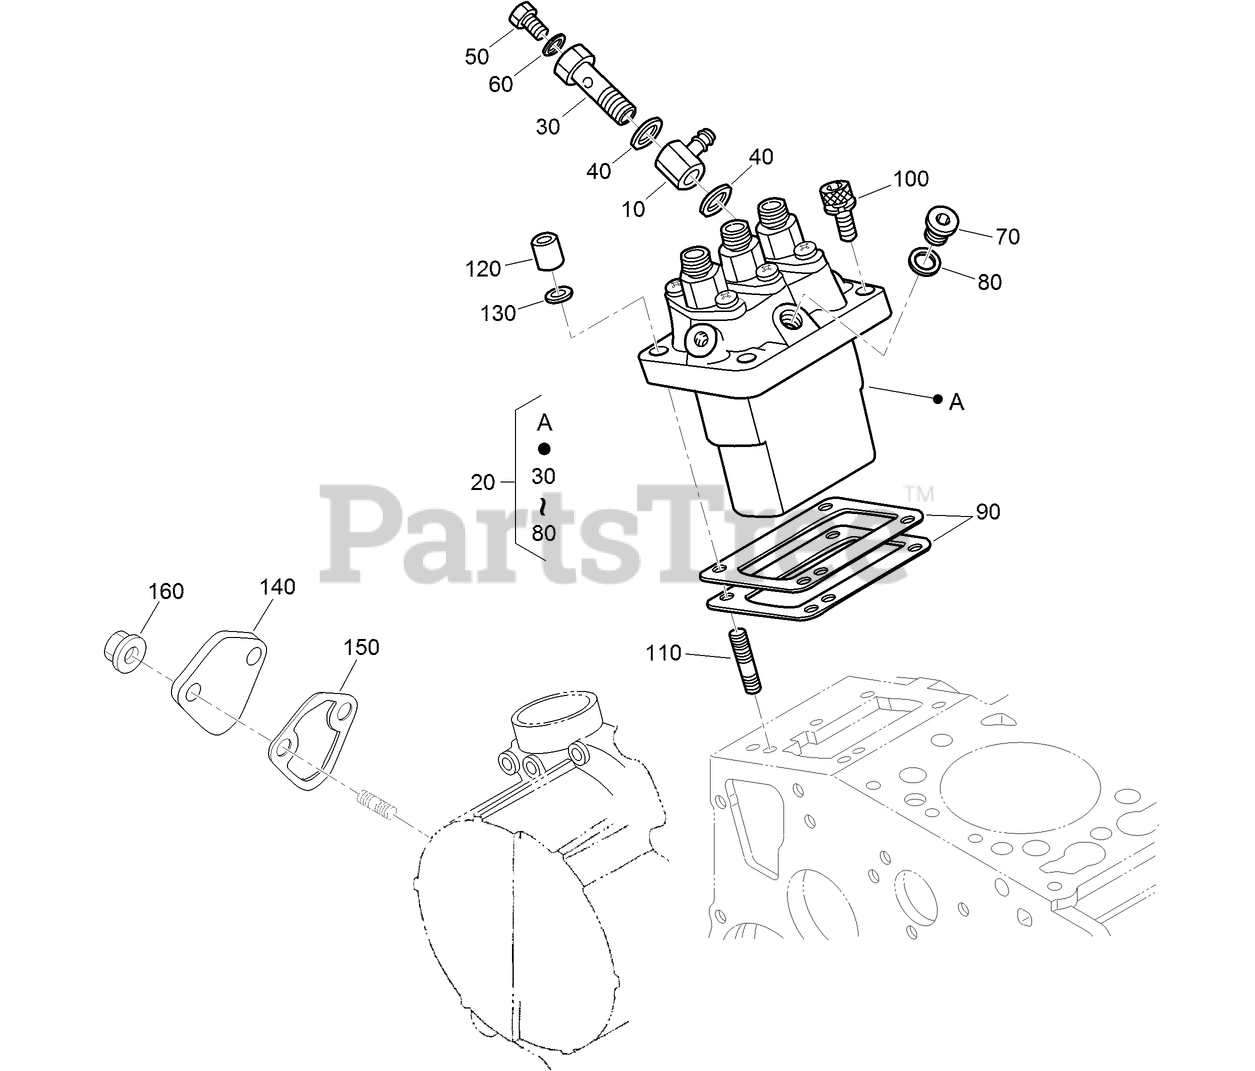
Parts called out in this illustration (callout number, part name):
10	JOINT-EYE
20	INJECTION PUMP ASM
30	BOLT-JOINT
40	GASKET
50	SCREW
60	GASKET
80	GASKET
90	SHIM-INJECTION (0.20MM)
90	SHIM-INJECTION (0.25MM)
90	SHIM-INJECTION (0.30MM)
90	SHIM-INJECTION (0.35MM)
90	SHIM-INJECTION (0.175MM)
100	BOLT-HEX SOC HD
120	NUT-CAP
130	WASHER-SPRING
140	COVER
150	GASKET-PUMP, FUEL
160	NUT-FLANGE
